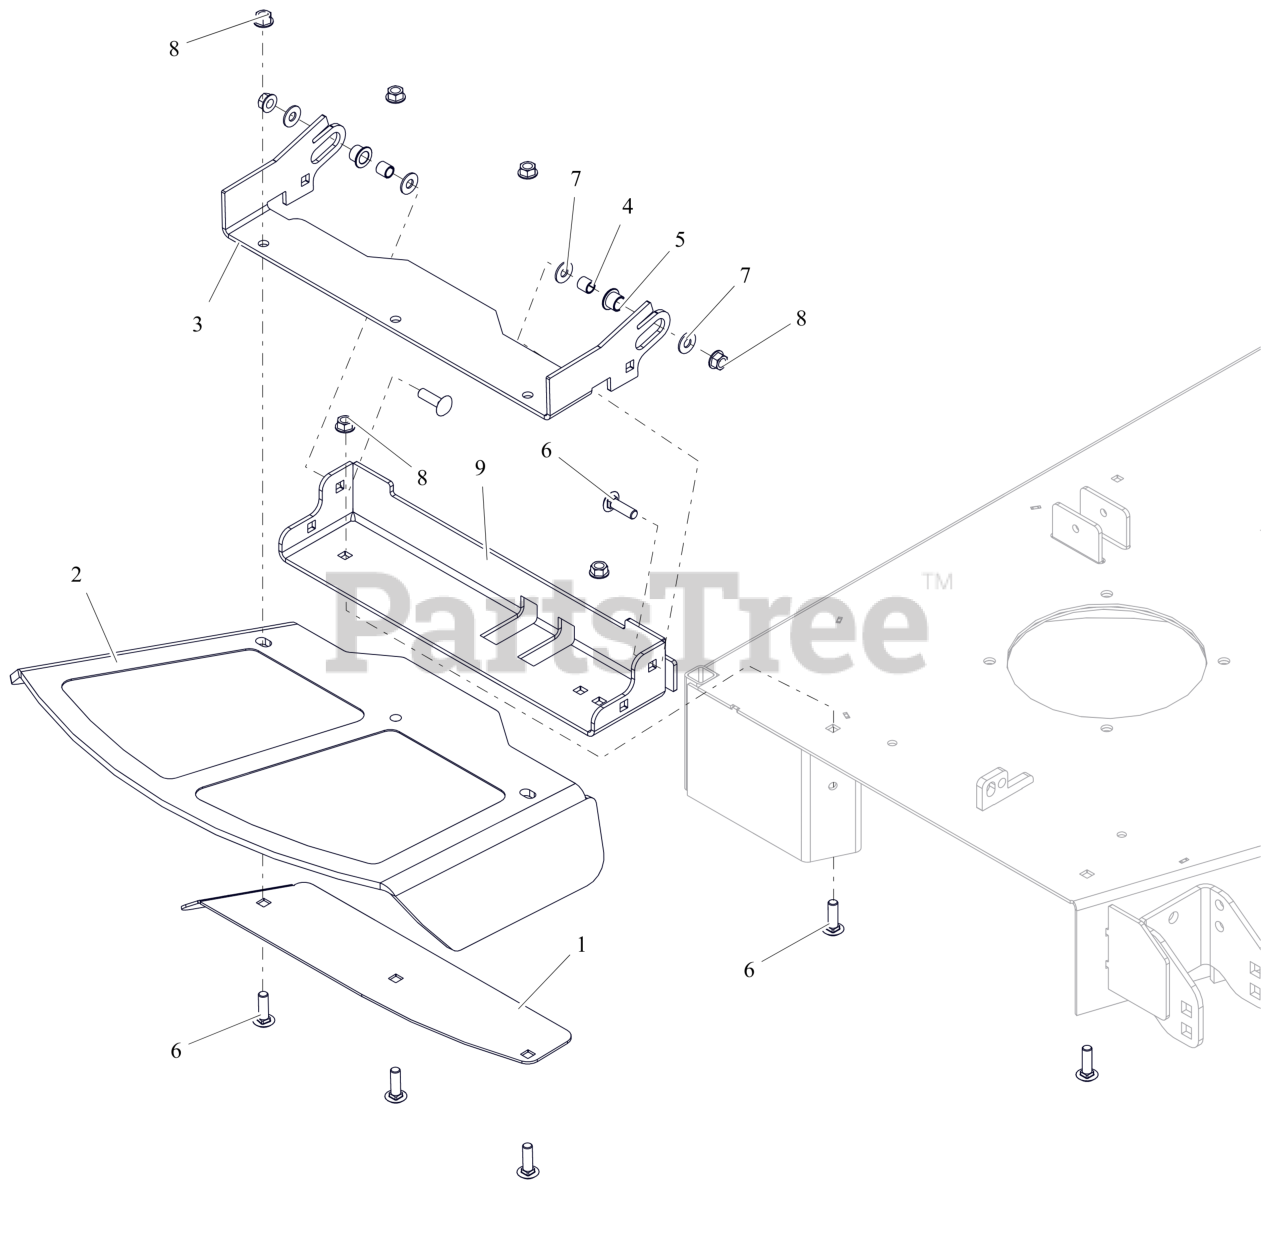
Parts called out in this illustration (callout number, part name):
1	48-60 DISCH CHUTE CLMP PLT-RED
2	CHUTE, FORMED RUBBER DISCHARGE
3	BRKT, CHUTE MOUNT (RED)
4	SPCR, .385X.500X.350
5	BSHG, FLANGED .50X.625X.50X.062
6	BLT,RHSSN .38-16X1.25 G5 ZCC
7	WSHR, HDND 0.375X0.875X0.064 ZCC
8	NUT-LK-CTR-FLG .375-16 GF ZCC
9	BASE, DISCHARGE CHUTE MTG BRKT (RED)
